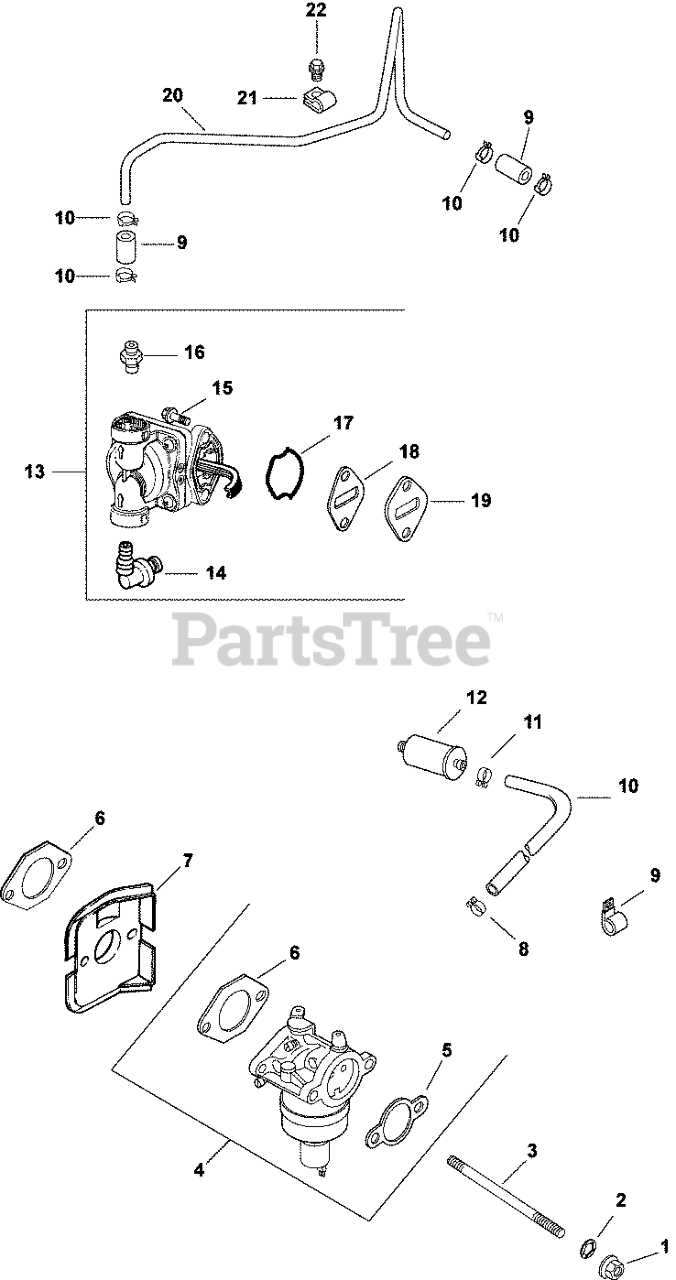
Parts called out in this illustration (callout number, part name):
1	NUT, FLG M6X1.0
2	WASHER, INT TOOTH LOCK 1/4"
3	STUD,M6X1.0X116
4	KIT, CARBURETOR - USE 12 853 178-S
5	GASKET, AIR CLEANER BASE
6	GASKET, AIR CLEANER BASE
7	DEFLECTOR, HEAT
8	CLAMP, BAND SPRING HOSE-(#2523737S)
9	CLIP, CABLE
10	HOSE,LW PERM.FUEL 24.00"-USE 25 111 81-S
11	CLAMP, HOSE (KM)-USE 25 237 31-S
12	FILTR,FUEL 75 MICRON (GRAVTY FEED)
13	KIT, FUEL PUMP
14	CONNECTOR, 90 DEG. HOSE
15	SCREW, LBD SKT M6x1.0x20-(#25086403S)
16	KIT, STRAIGHT FITTING
17	GASKET, FUEL PUMP
18	SPACER, FUEL PUMP
19	O-RING, FUEL PUMP
20	LINE, FUEL
21	CLIP, TUBE & WIRING (KM)
22	SCREW, FLG THD FRM M5X.8X10
1285395-S	KIT, CARB W/GASKETS - USE 12 853 93-S
